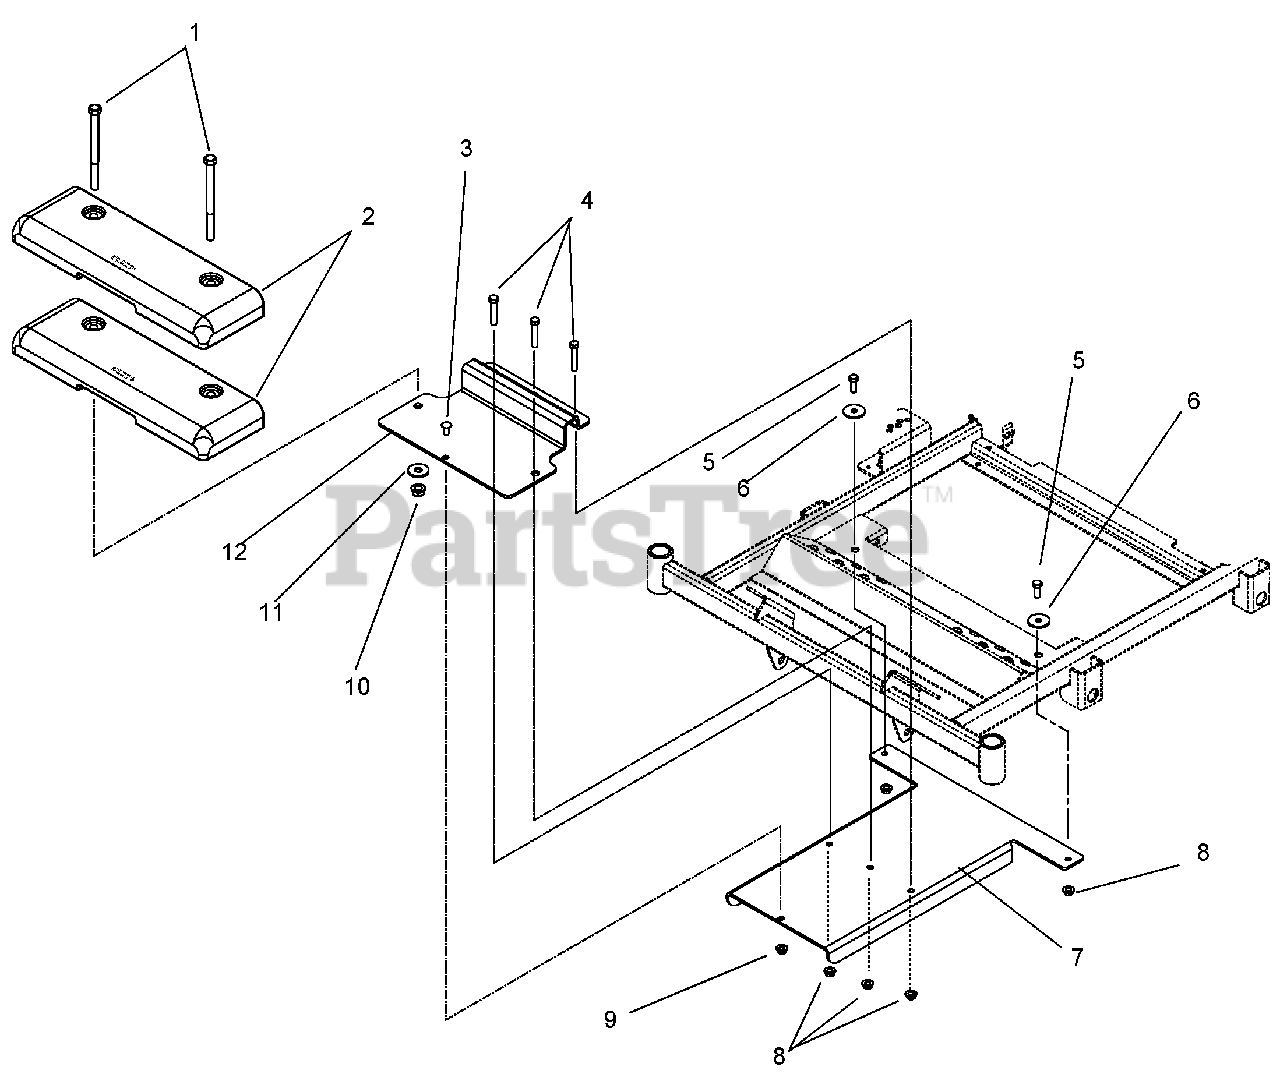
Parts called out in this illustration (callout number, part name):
1	Bolt, Hex .50-13 x 5.00 Grade 5
2	Counterweight
3	Bolt, Round Head Square Neck, .312-18 x .75 Grade 5
4	Bolt, Hex .38-16 x 2.00 Grade 5
5	Bolt, Hex .38-16 x 1.00 Grade 5
6	Washer, Flat Steel .390 x 1.50 x .125
7	Bracket, Weight Mount
8	Nut, .38-16 Nyloc Flange
9	Nut, Nylon Flange .312-18
10	Nut, Top-Locking Flange .50-13
11	Washer, Flat Steel .511 x 1.44 x .125
12	Bracket, Bagger Axle Mount
